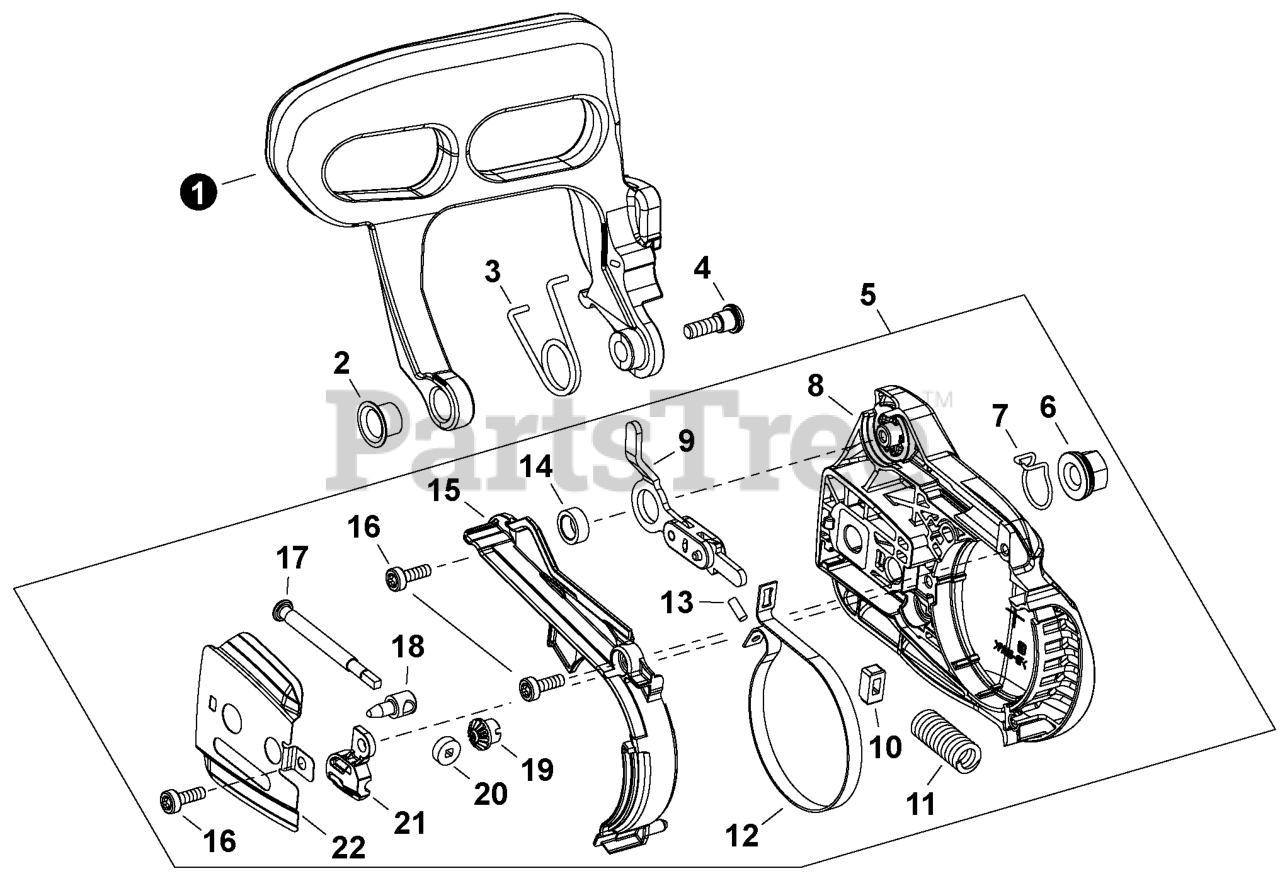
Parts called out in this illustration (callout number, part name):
1	LEVER, BRAKE
2	COLLAR 10
3	SPRING, TORSION
4	BOLT 5x13
5	SPROCKET GUARD ASSY
8	GUARD, SPROCKET
9	CONNECTOR, BRAKE
11	SPRING, COMPRESSION
12	BAND, BRAKE
14	COLLAR 8
15	COVER, BRAKE
16	BOLT, TORX 4x12
18	TENSIONER, CHAIN
19	GEAR, BEVEL
20	GEAR, BEVEL
21	COLLAR 8
22	PLATE, GUIDE - OUTER
